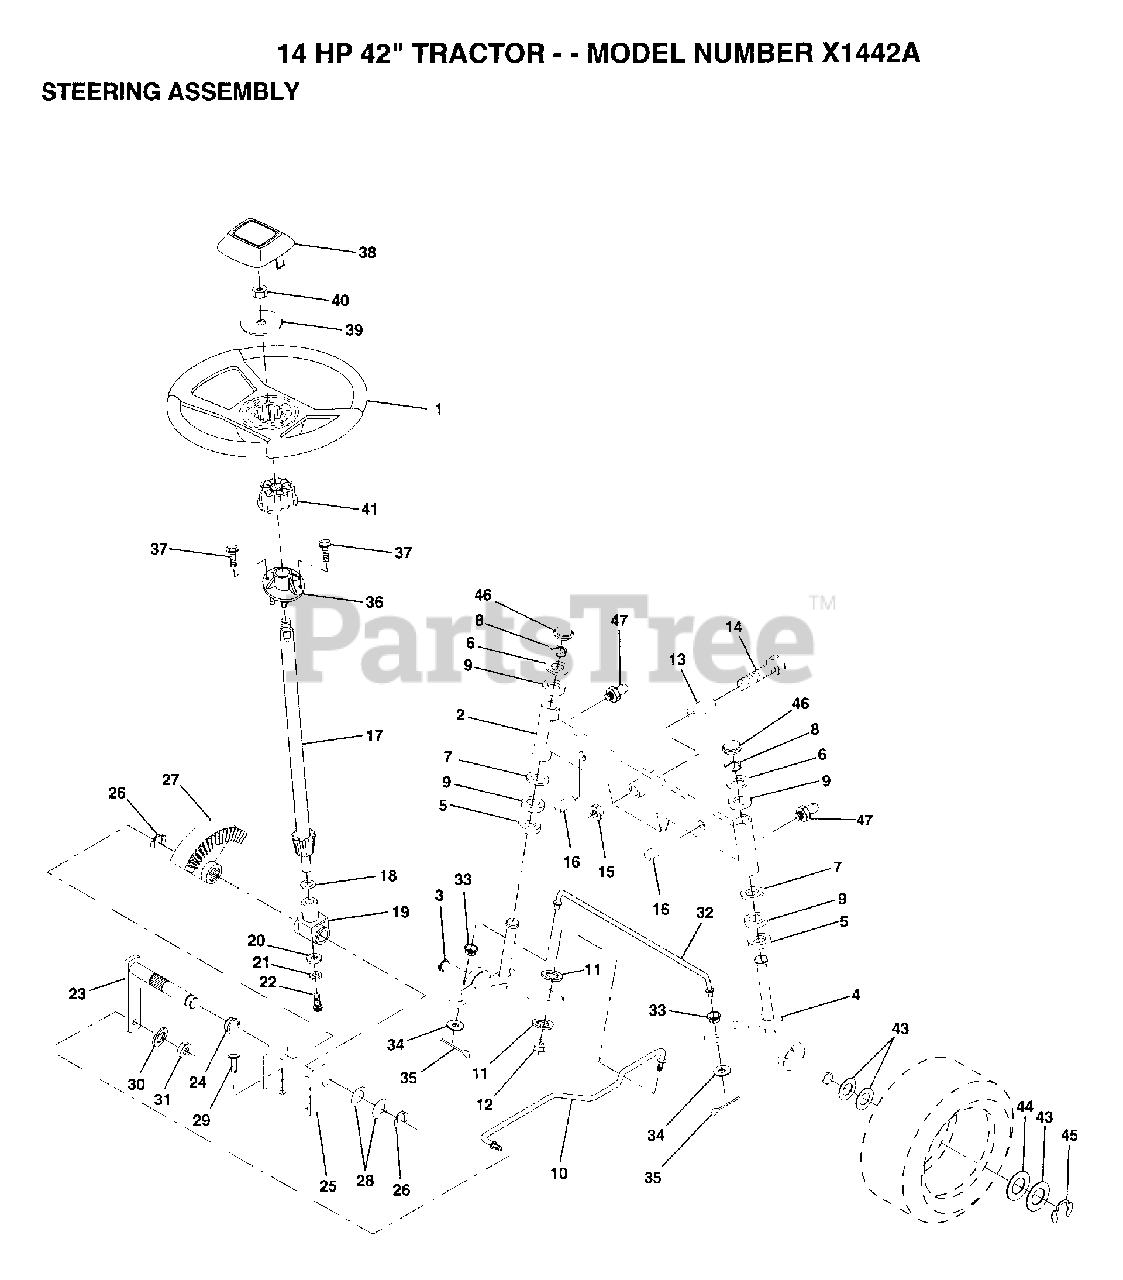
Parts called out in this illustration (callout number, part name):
3	SPINDLE LH
4	SPINDLE RH
5	WASHER .T
6	WASHER
7	WASHER
8	RING
9	COL. SRTG. BEAR.
11	LOCKWASHER
13	BEARING
14	BOLT HEX 5/8-11
15	"NUT-LOC,FLANGE LT"
16	AXLE PIN
17	STEERING SHAFT
18	THRUST WASHER
19	SUPPORT.SHAFT
21	LOCKWASHER
22	"SCREW,SPECIAL"
24	NYLINER T
25	"BRKT,STEERING"
26	RING
27	GEAR SECTOR
28	WASHER .T
29	SCREW
30	LOCKWASHER
32	TIE ROD
33	BUSHING.DRAGLINK
34	WASHER
35	COTTER PIN
38	ST WHL INSERT CAP
39	WASHER
41	ADAPTER LT
43	WASHER
44	WASHER
45	RING
46	CAP
47	ZERK M
